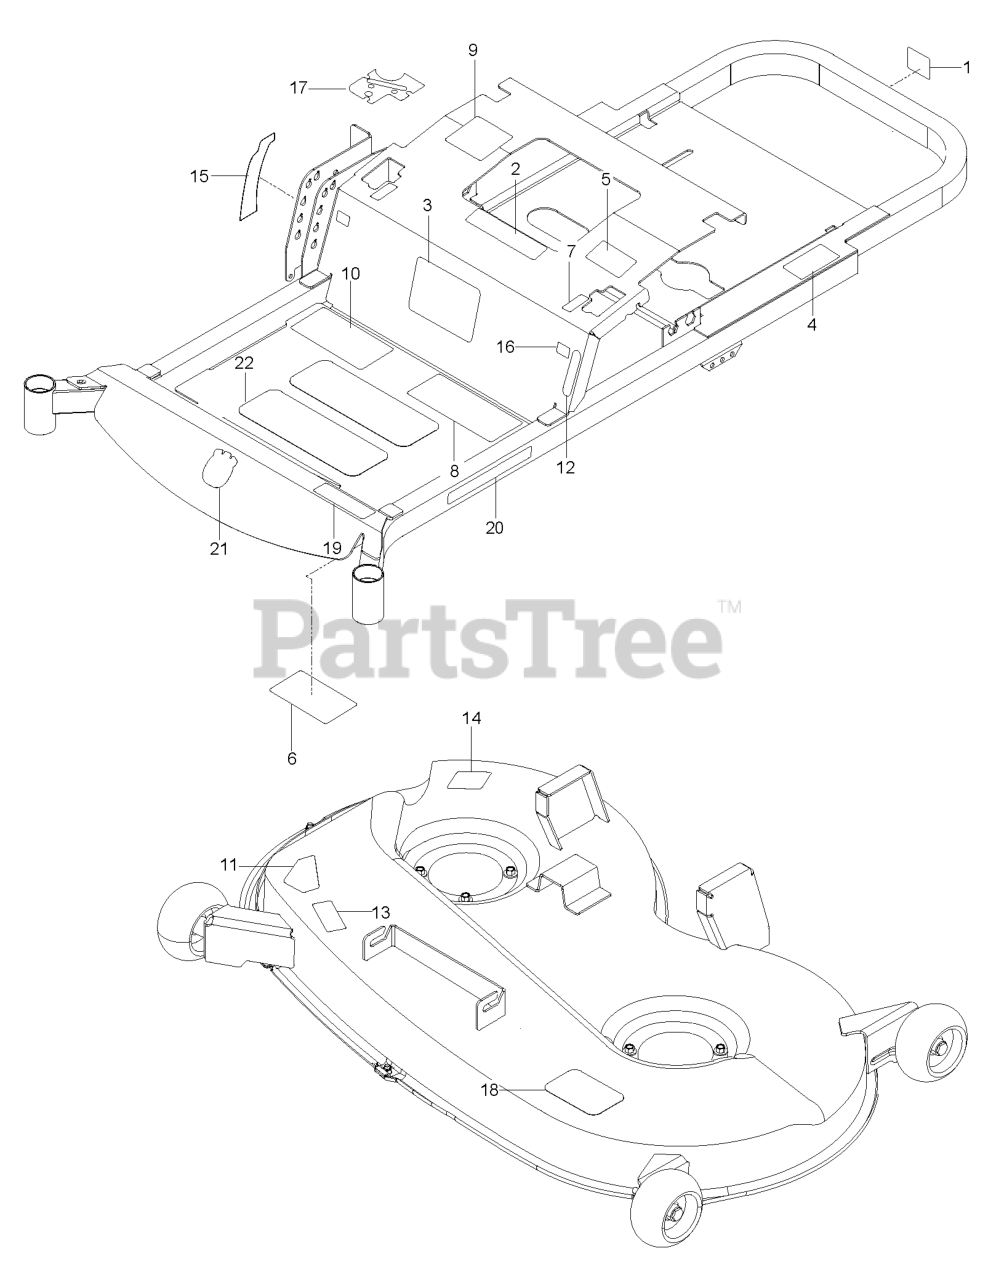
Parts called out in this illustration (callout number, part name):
1	DECAL, PROP. 65
2	EURO DECAL-BATTERY WARNIN6
3	DECAL, START
4	DECAL, DO NOT TOW
5	DECAL, EXITING MOWER
6	DECAL, SERVICE
7	DECAL, MOTION CONTROL
8	DECAL, SAFETY WARNING
9	DECAL, CUSTOMER RESPNSIBILITY
10	DECAL, WARNING
11	DECAL, CPSC
12	DECAL, PARK BRAKE
13	DECAL, EURO SEVERING
14	DECAL, CAUTION
15	DECAL, HEIGHT
16	DECAL, F.S.T.
17	DECAL, CTRL PANEL HUS WO CHOKE
18	DECAL, BELT ROUTING
19	DECAL, RZ4621 (BF UNIT)
20	RP.DECAL.BADGE.170MM.TEXTLOGO
21	DECAL.AUGER.HUSQ.CROWN.SNOW
22	ANTI-SKID PAD
